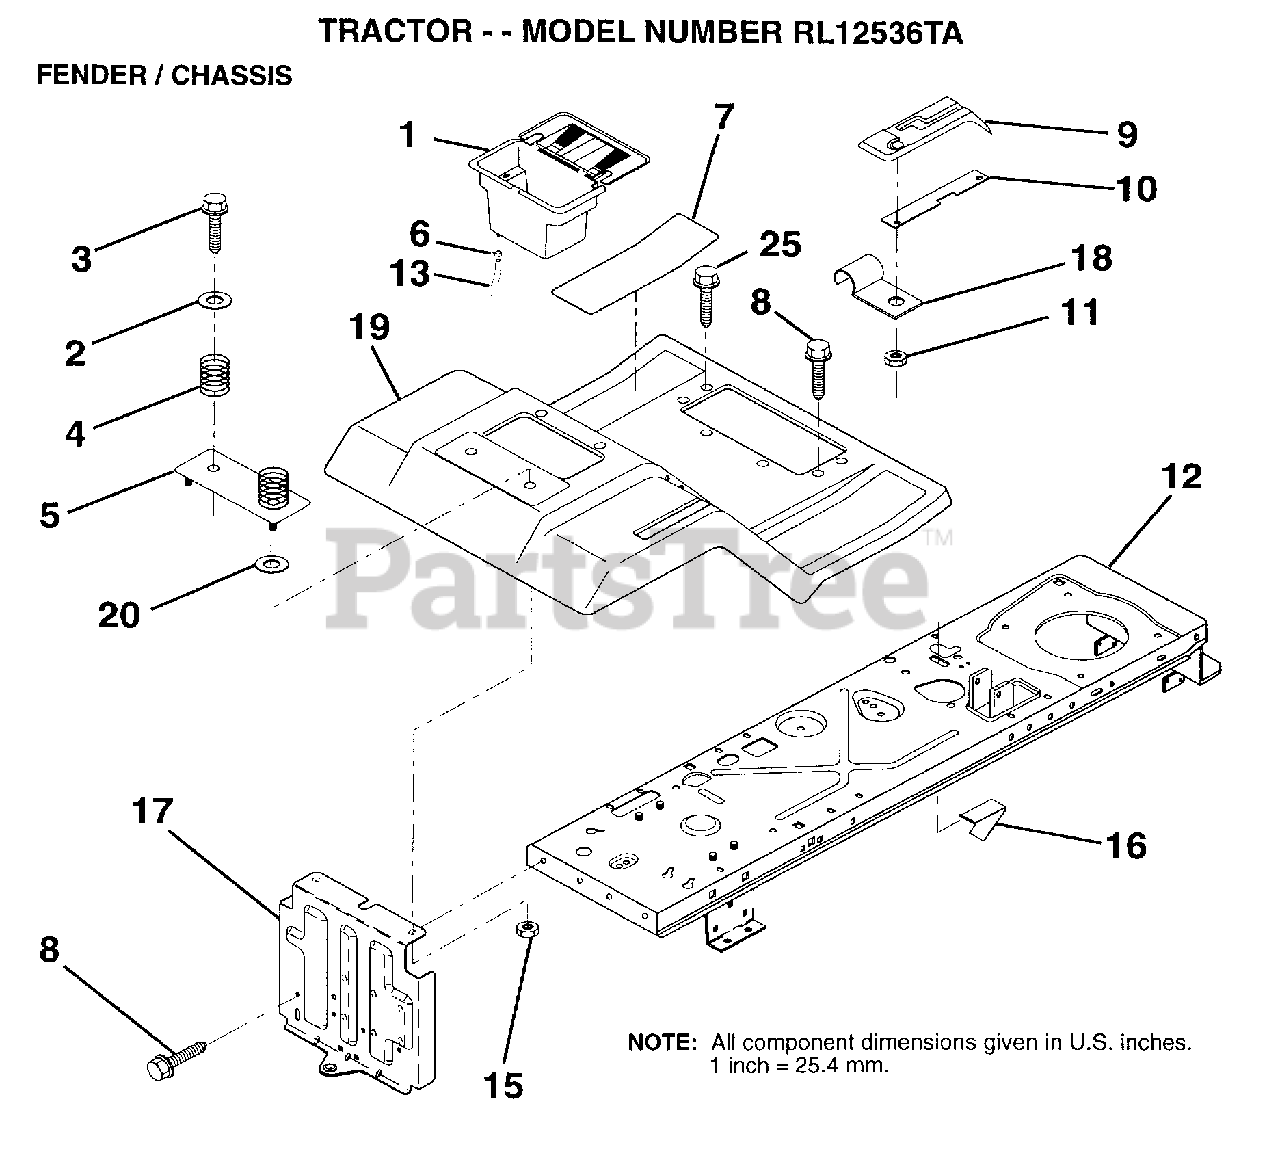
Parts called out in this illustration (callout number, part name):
2	WASHER
3	SCREW
4	SPRING COMPRESSIO
5	BTRY FENDER PLATE
6	HOSE CLAMP T
7	PAD FOOTREST
8	SCREW
9	CONSOLE SHFT 5SP
10	PLATE LOCK SHIFT
11	NUT
12	CHASSIS.WELD.ASM.
13	TUBE T
15	NUT HXKEP 1/4X20
17	DRAWBAR ASM LR
18	"CLIP,INSULATOR"
19	FENDER/FOOT MS505
25	SCREW TI
